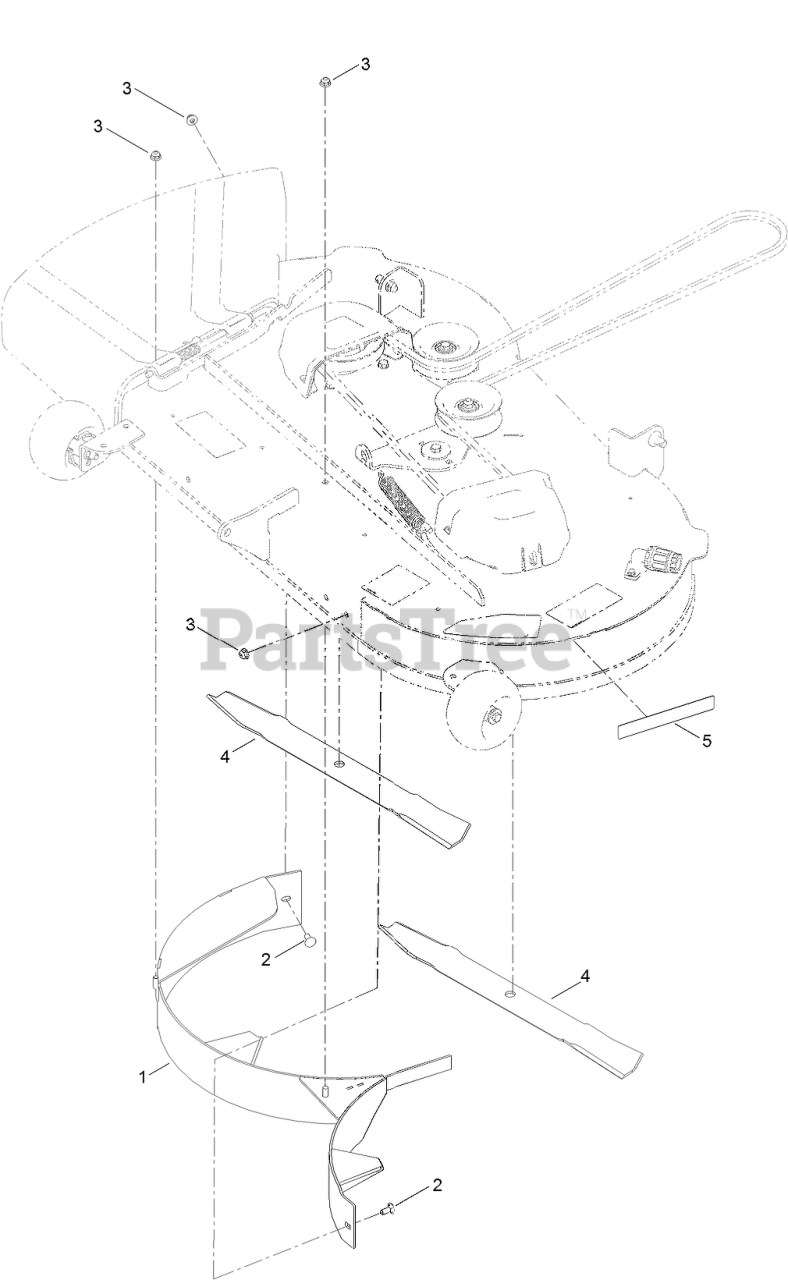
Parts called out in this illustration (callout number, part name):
1	BAFFLE-RECYCLING
2	BOLT-CARR
3	NUT-HF
4	BLADE-MULCH
5	DECAL-RECYCLER
